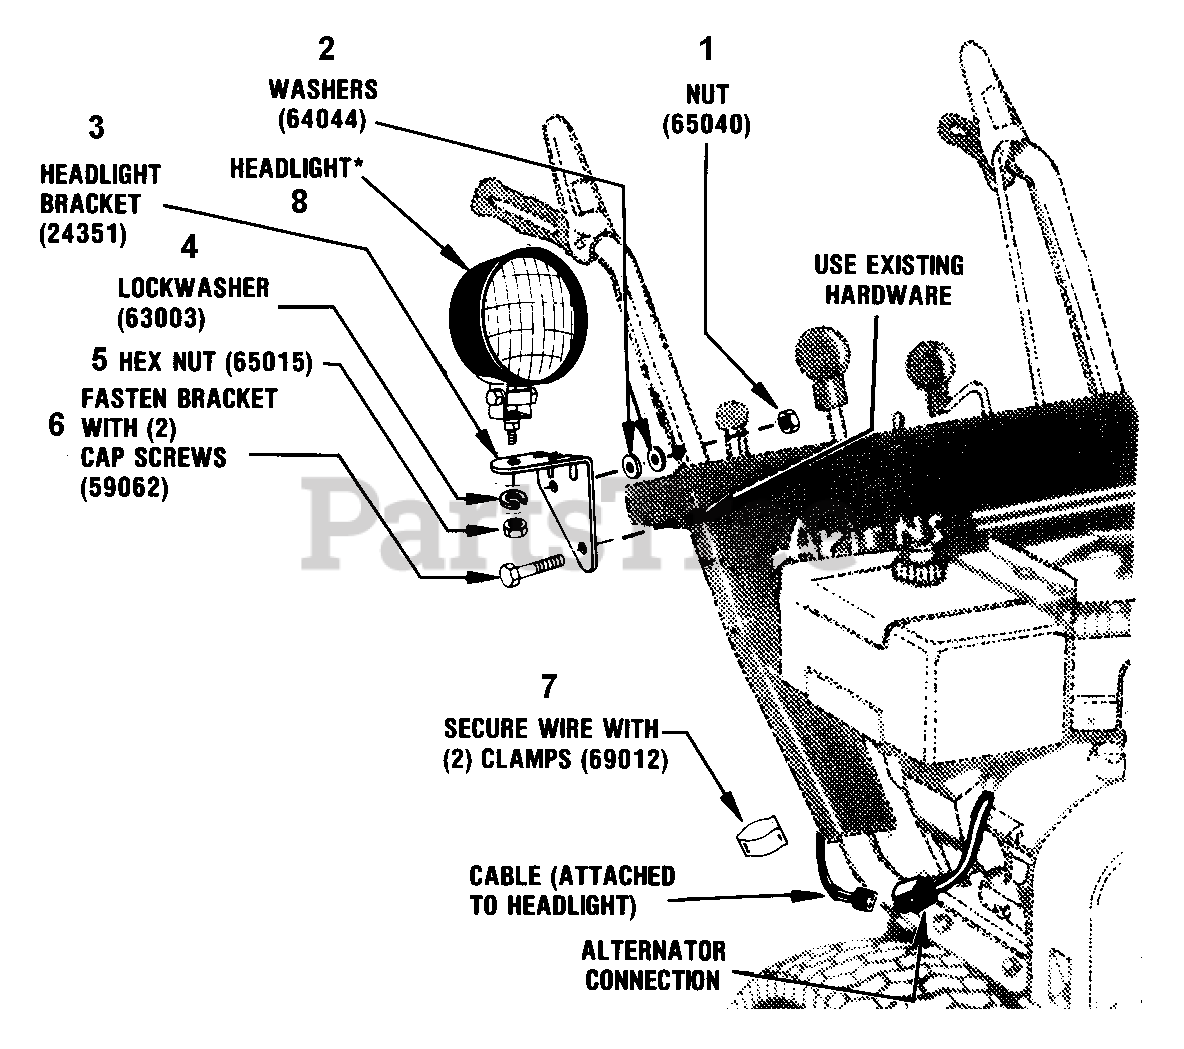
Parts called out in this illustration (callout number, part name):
1	NUT-LK-CTR .250-20 PL
2	WSHR-FL-STL .380X.875X.179 PL
3	HEADLAMP BRACKET
4	WSHR-LK .312X.097 PL HVY
5	NUT-HEX .312-18
6	BLT-HEX .25-20X1.75 PL GR2
8	HEADLIGHT
8	HEAD LIGHT
8	HEAD LAMP ASSEM. ALTERNATE 62
8	LAMP ASSY
8	TERMINAL
8	CONNECTOR
8	SWITCH - HEADLIGHT
8	BOOT - HEADLIGHT SWITCH
8	U BRACKET
8	BLT-HEX .31-18X2.00 PL GR2
8	BLT-RDHDSQNK .31-18X1.00 PL
8	WSHR-LK .312X.097 PL HVY
